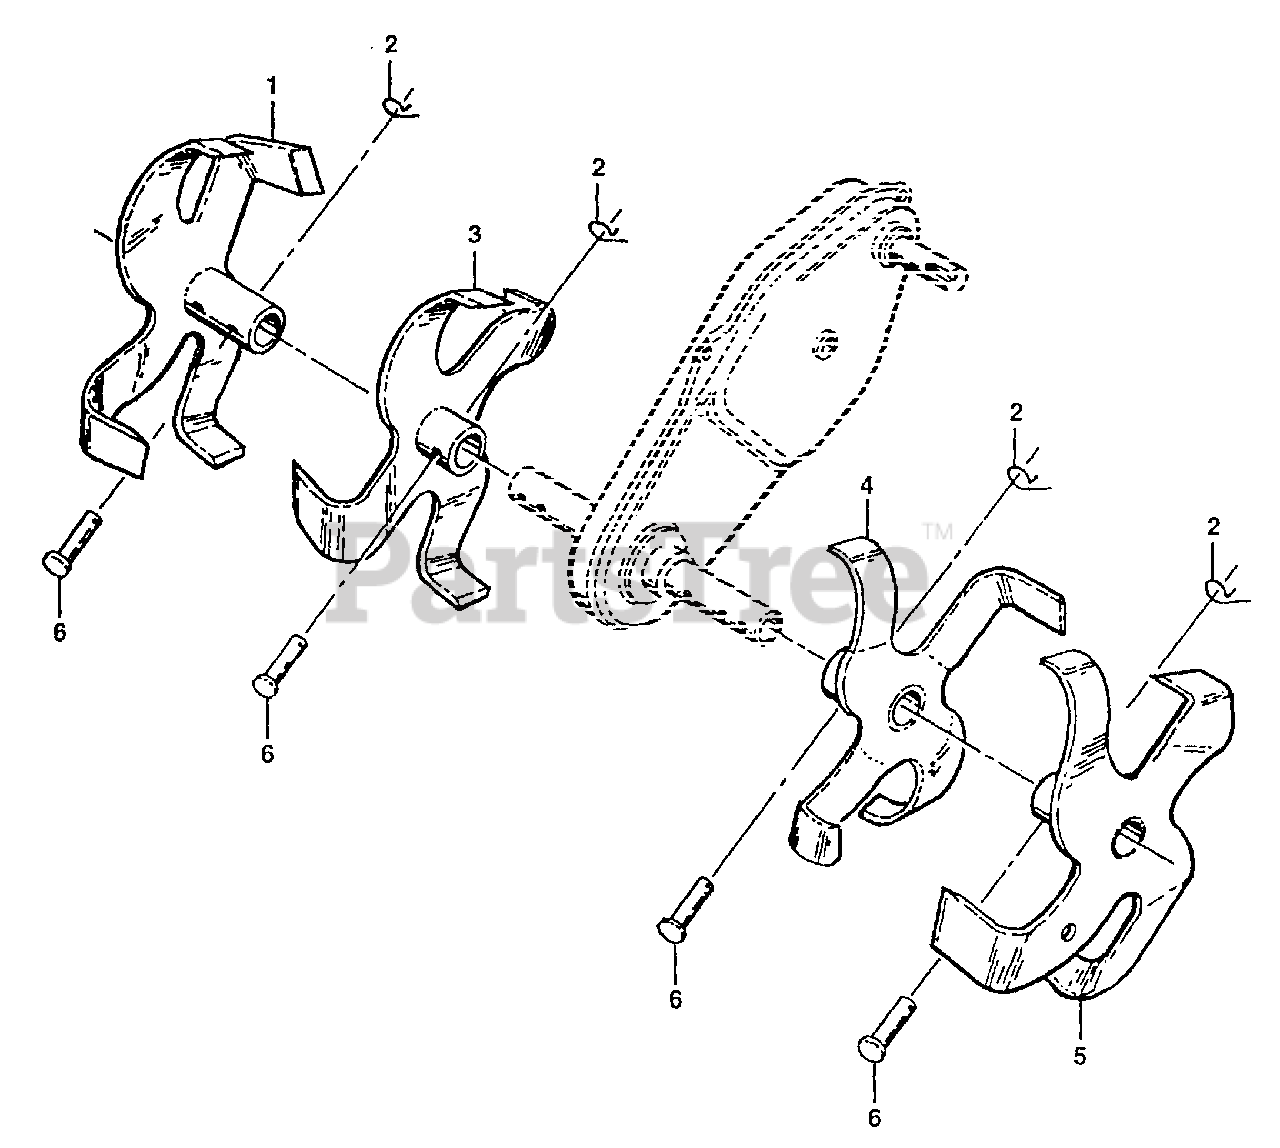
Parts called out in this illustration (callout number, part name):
1	Tine, Outer, R.H.
2	Clip, Hairpin
3	Tine, Inner, R.H.
4	Tine, Inner, L.H.
5	Tine, Outer, L.H.
6	Pin, Clevis
